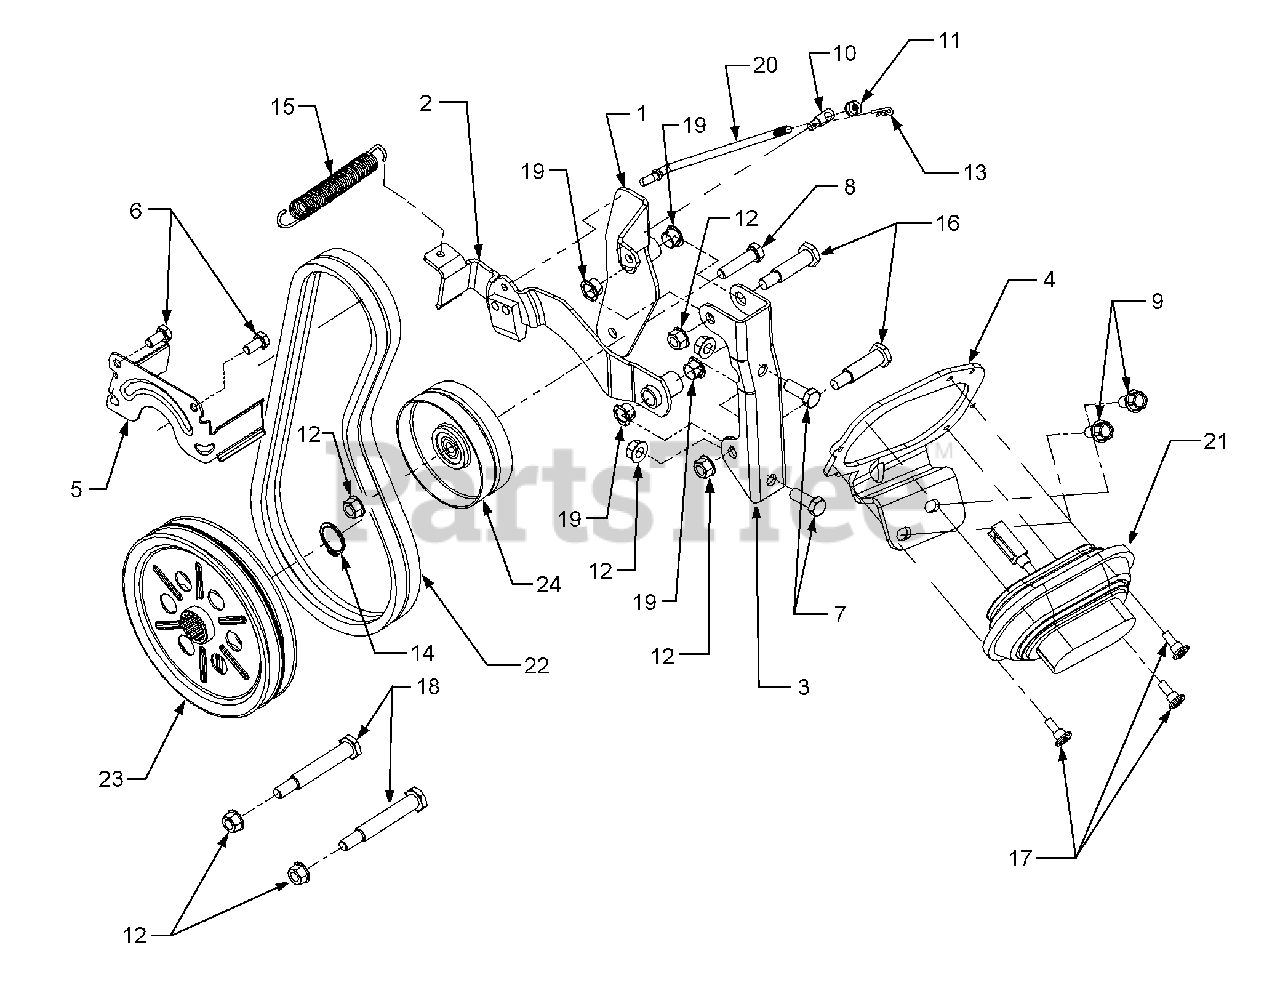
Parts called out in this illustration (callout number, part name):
2	Bracket Assembly, Brake
6	Screw, Hex Cap 5/16-24 x .625 GR5
7	Screw, Hex Cap 3/8-16 x 1.0 GR5
8	Screw, Hex Cap 3/8-16 x 1.5 GR5
9	Screw, Hex Wash. Hd. Tapp 3/8-16 x .75
10	Ferrule, Brake Adjustment
11	Nut, Hex Insert Lock, 1/4-20
12	Nut, Flange Lock, 3/8-16
13	Pin, Internal Cotter
14	Snap Ring, 1.0 Dia Shaft
15	Spring, Extension, .530 x 4.74
16	Shoulder Screw, .498 x 1.45
17	Shoulder Screw, .375 x .28
18	Shoulder Screw
19	Bearing, Nylon Flange
20	Rod, PTO Brake
21	Vacuum Actuator
22	V-Belt, A-Section x 37.63
23	Pulley, PTO Drive. 6.75-Double
24	Pulley, Flat Idler, 4.0
